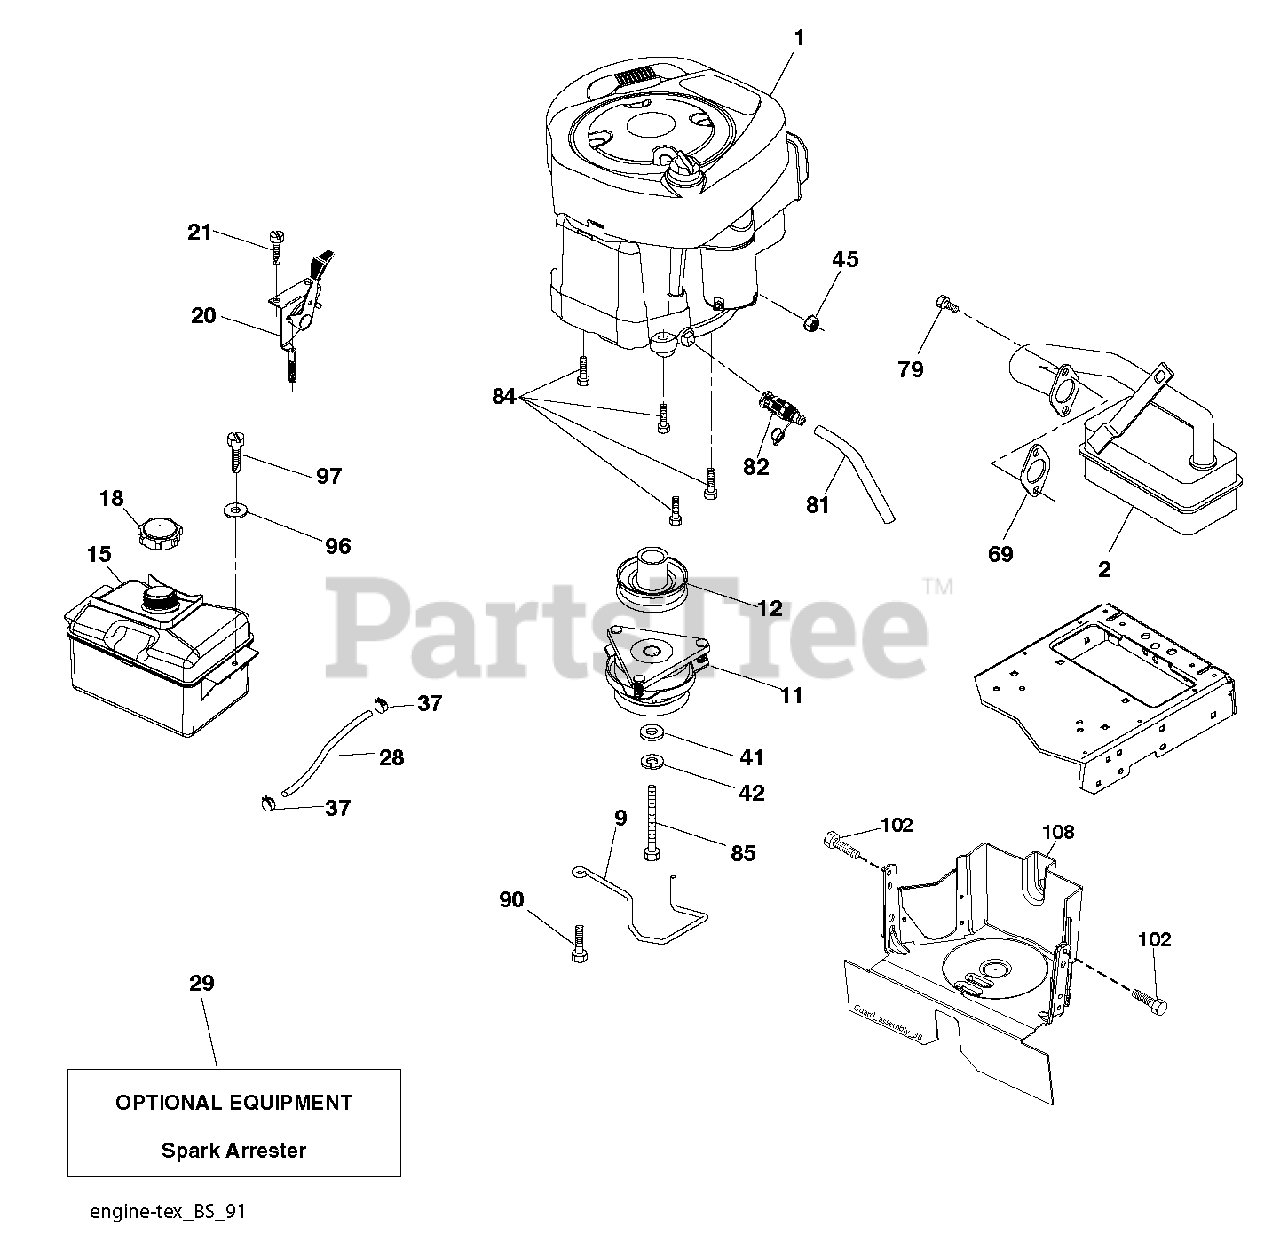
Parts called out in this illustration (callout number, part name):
2	MUFFLER.LT.BRIGGS.14HP.IC/OHV
9	KEEPER BELT ENGINE
11	CLUTCH.ELECTRIC.LT.48"*
12	PULLEY.ENGINE.TUFFTORQ
15	FUEL.TANK.ASM.NON-EPA
18	CAP ASM.FUEL.2.25"FR.
20	CONTROL.TH/CK.C.
21	SCREW.#10 X 0.750.BOS
28	LINE.FUEL.20
29	KIT.SPARK ARRESTOR 794945 B&S
37	HOSE CLAMP
42	LOCKWASHER
45	NUT
69	REPL BY 532 27 22-93
79	SCREW.SOCKET HD.5/16-1
81	TUBE, DRAIN OIL ASM.
82	VALUE.OIL.DRAIN
84	SCREW.3/8-16
85	BOLT HEX 7/16-20X4-1/4"
90	SCREW 3/8-16X1
97	SCREW HEXWSHR 1/4-20X3/4
102	SCREW 5/16-18X1
108	COVER PULLEY
